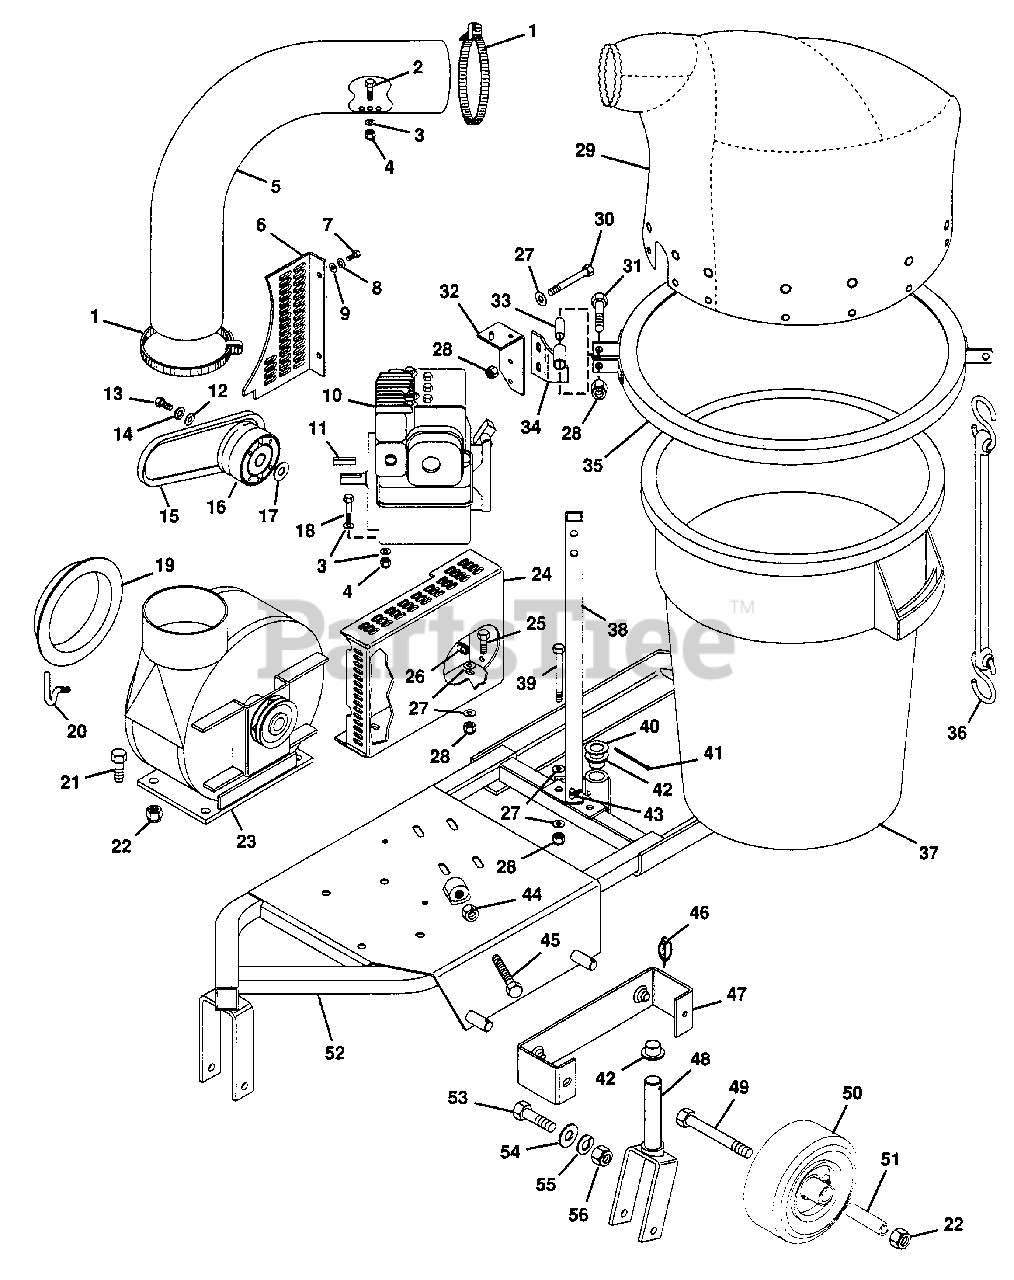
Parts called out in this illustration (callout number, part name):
1	Clamp
2	Bolt, Hex 5/16-18x1.00
3	Washer, Flat .344x.688x.065
4	Nut, Lock 5/16-18
5	Tube, Catcher
6	Cover, Guard
7	Bolt, Hex 1/4-20x.75
8	Washer, Lock 1/4 Reg.
9	Washer, Flat .281x.625x.065
10	Engine, 5.2 HP Kawasaki
11	Key, Hub .187x1.500
12	Washer, Flat .313x.875x.065
13	Bolt, Hex 5/16-24x.75
14	Washer, Lock 5/16 Reg.
15	V-Belt
16	Clutch
17	Race, Bearing Thrust .060
18	Bolt, Hex 5/16-18x1.75
19	Adaptor, Hose
20	Handle, Locking
21	Bolt, Hex 1/2-13x1.25
22	Nut, Lock 1/2-13
23	Assembly, Blower Housing
24	Guard
25	Bolt, Hex 3/8-16x.875
26	Nut, Retainer
27	Washer, Flat .406x.812x.065
28	Nut, Lock 3/8-16
29	Cover, Grass Catcher
30	Bolt, Hex 3/8-16x2.50
31	Bolt, Hex 3/8-16x2.00
32	Bracket, Tube
33	Bushing, .385x.625x1.00
34	Weldment, Pivot Bracket
35	Weldment, Ring
36	Strap, Hold Down
37	Can, Grass
38	Weldment, Ring Support
39	Bolt, 3/8-16x3
40	Race, Bearing Thrust
41	Pin, Cotter .125x1.500
42	Bearing, Flanged
43	Fitting, Lube 90 Degree
44	Nut, Hex 3/8-16
45	Bolt, Hex Spec. 3/8-16x3.00
46	Pin, Klik
47	Weldment, Catcher Mount
48	Weldment, Caster
49	Bolt, Hex 1/2-13x5.50
50	Wheel, Wing Gauge
51	Bushing, Axle
52	Weldment, Catcher
53	Bolt, Hex 5/8-11x2.50
54	Washer, Flat .656x1.312x.095
55	Washer, Lock 5/8 SP
56	Nut, Lock 5/8-11
NS	Bar, Reinforcing
